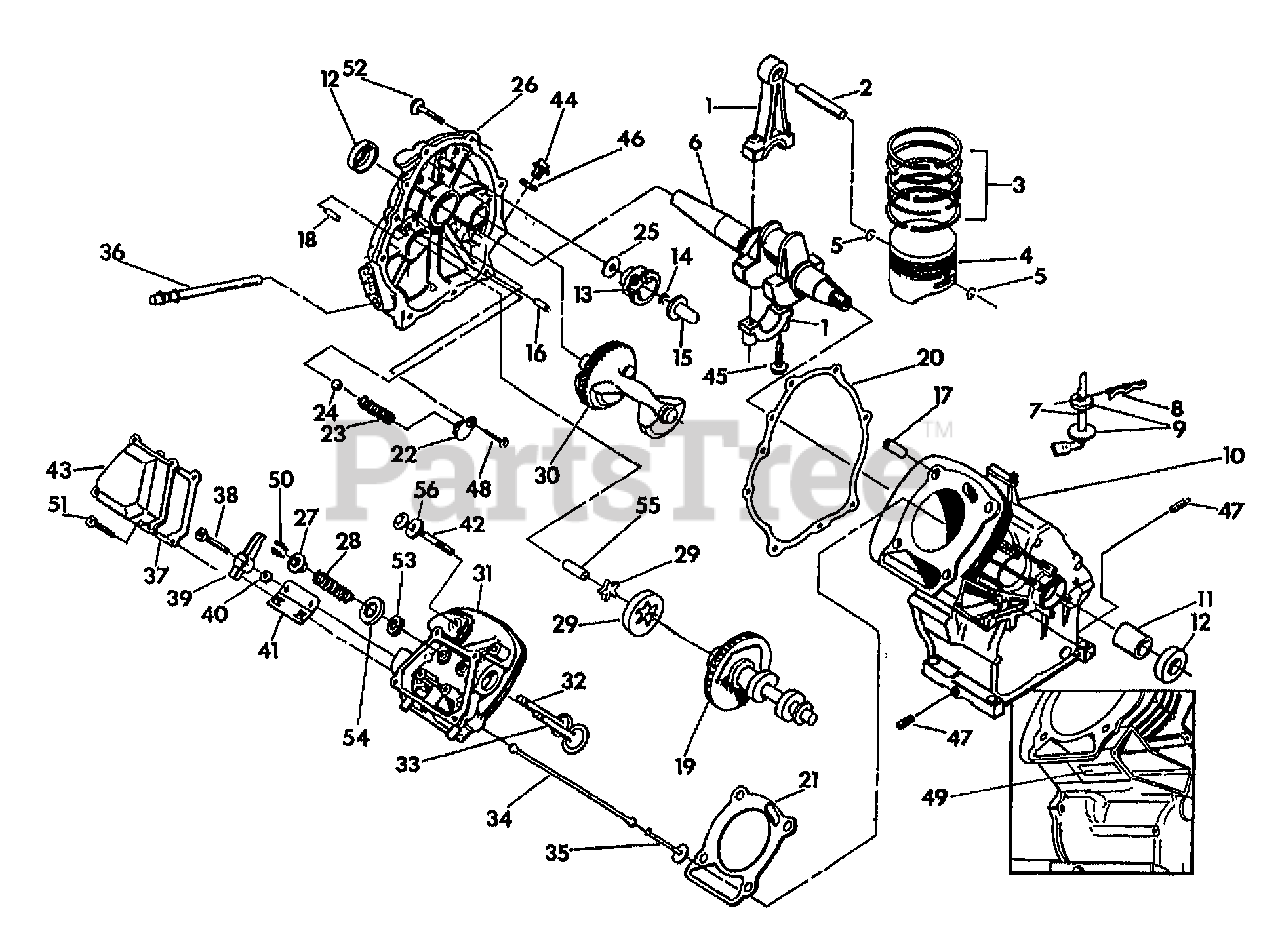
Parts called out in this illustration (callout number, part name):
1	ROD-CONNECTING W/CAP&BOLT
2	PIN-PISTON GN360
3	PISTON RING SET (6000W GEN)
4	PISTON (6000W GEN)
5	RETAINER-PISTON PIN (6000W GEN
6	ASSM-CRANKSHAFT W/GEARS (6000
7	ARM-GOVERNOR (6000W GEN)
8	PIN-"R" GOVERNOR ARM
9	WASHER-GOVERNOR ARM
10	CRANKCASE-HS W/TAPER PLUGS
11	BEARING-SLEEVE (6000W GEN)
12	SEAL-CRANKSHAFT (6000W GEN)
13	ASSM-GOVERNOR GEAR (6000W GEN)
14	RETAINER-GOVERNOR ("C" RING)
15	SPOOL-GOVERNOR
16	DOWEL-12"DIA. SLEEVE
17	DOWEL-SLEEVE 014 (6000W GEN)
18	DOWEL-SOLID 012 (6000W GEN)
19	ASSM-CAMSHAFT (6000W GEN)
20	GASKET-CRANKCASE (6000W GEN)
21	GASKET-CYL HEAD (6000W GEN)
22	RETAINER-SPRING OIL PRESS.
23	SPRING-PRESSURE RELIEF (6000WG
24	BALL-PRESSURE RELIEF
25	WASHER-THRUST
26	COVER-GEAR ASSM GN360
27	RETAINER-VALVE SPRING (6000 GE
28	SPRING-VALVE (6000W GEN)
29	GEROTOR SET (6000W GEN)
30	BALANCER (6000W GENERATOR)
31	CYL HEAD W/VALVE SEATS & GUIDE
32	VALVE-EXHAUST (6000W GEN)
33	VALVE-INTAKE (6000W GEN)
34	ROD-PUSH GEN #88396A
35	TAPPET (6000W GENERATOR)
36	ASSM-OIL PICK-UP (6000W GEN)
37	GASKET-ROCKER CVR (6000W GEN)
38	STUD-PIVOT BALL (6000W GEN)
39	ARM-ROCKER (6000W GENERATOR)
40	NUT-HEX/JAM GN360
41	PLATE-PUSH ROD GUIDE (6000 GEN
42	BOLT-HEAD M10X100 (6000 GEN)
43	ASSM-ROCKER CVR BREATHER (GEN)
44	PLUG-OIL FILL
45	BOLT-CONNECTING ROD (6000 GEN)
46	RING-O 17.8MM IDX2.4MM
47	PLUG-3/8" NPT PIPE (6000 GEN)
48	SCR M5-0.8X8MM (THD FORMING)
49	DECAL-SER. NO. S360H
50	VALVE SPRING KEEPER (6000 GEN)
51	SCR M6-1.0X12MM
52	SCR-HFLK M8-1.25X45
53	SEAL-VALVE STEM (6000W GEN)
54	WASHER-VALVE SPRING (6000 GEN)
55	SHAFT-GRTR BRG TUBE (6000W GEN
56	WASHER-CYL HEAD (6000W GEN)
